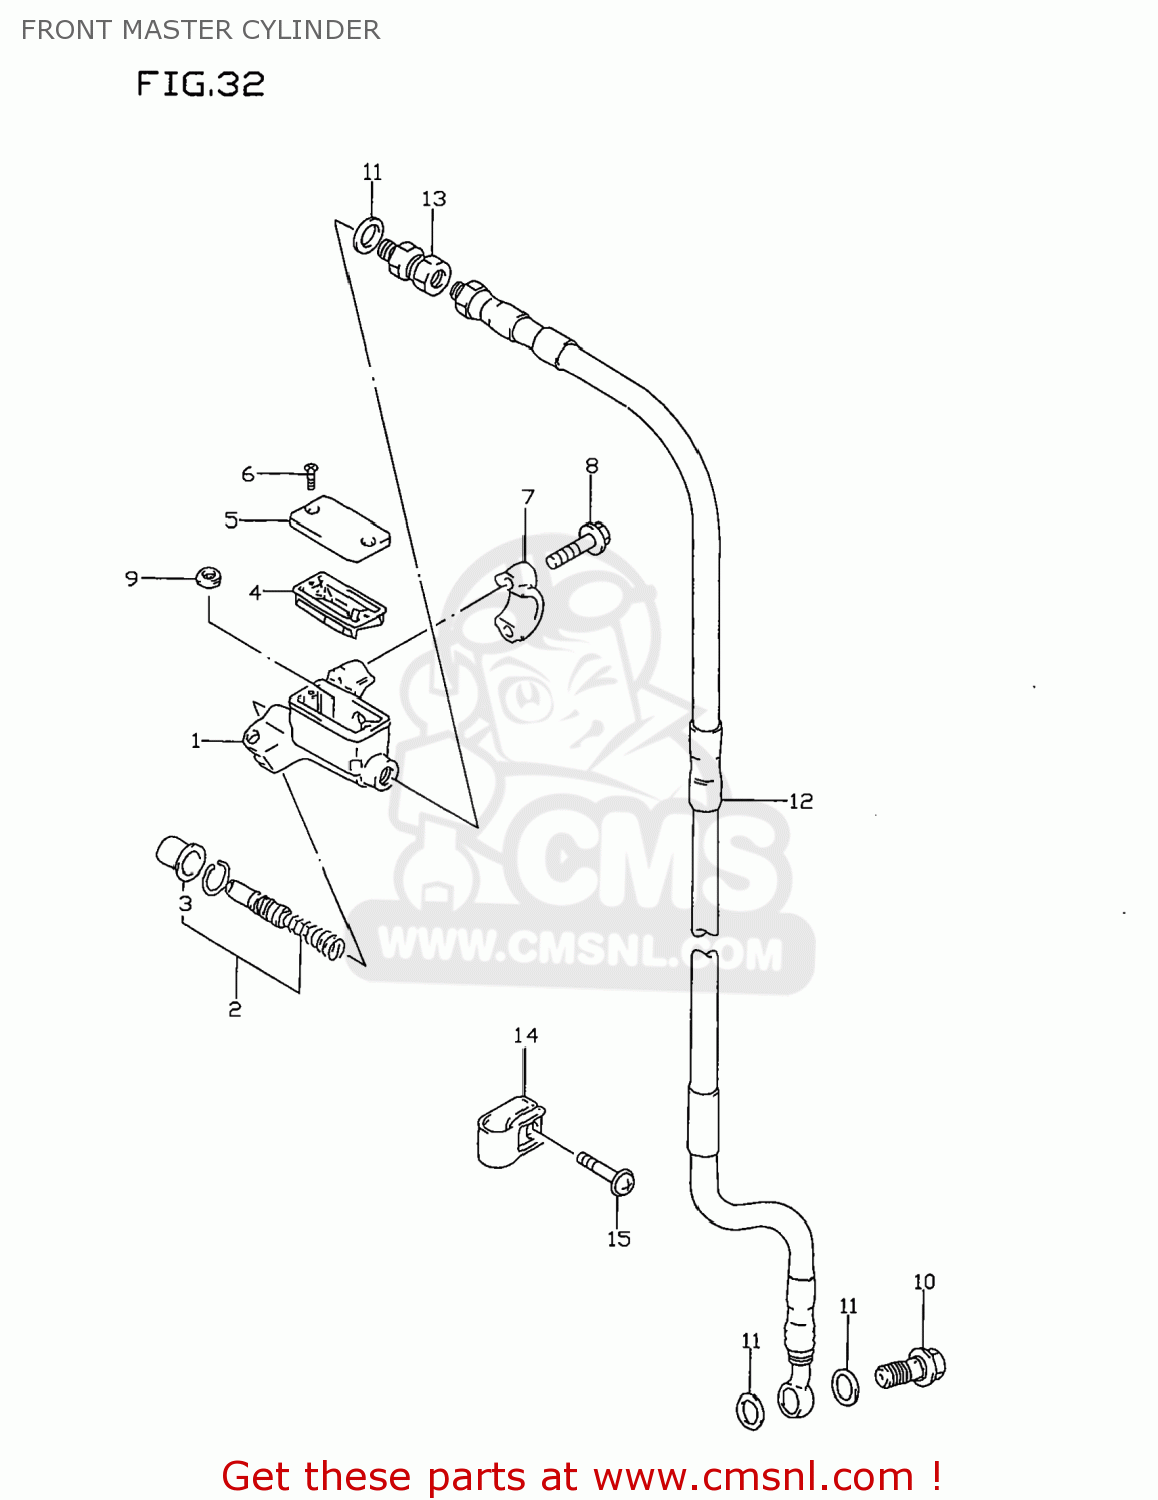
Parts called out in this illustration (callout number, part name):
1	CYLINDER ASSY,FR MASTER
2	PISTON & CUP SET
3	BOOT
4	DIAPHRAGM
5	CAP
6	SCREW
7	HOLDER
8	BOLT
9	SEPARATOR
10	BOLT UNION
11	WASHER(10X15X1.5)
12	HOSE,FR BRAKE
13	ADAPTOR,BRAKE HOSE
14	CLAMP,FR BRAKE
15	SCREW
